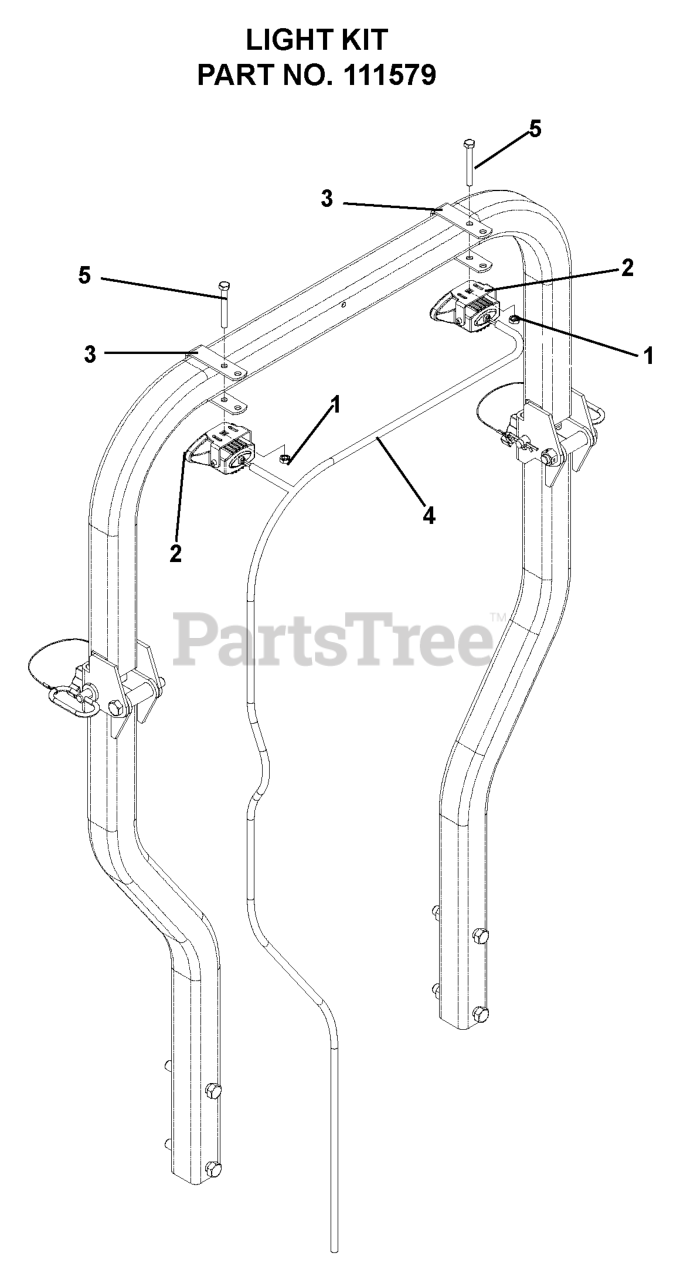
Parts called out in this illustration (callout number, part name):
1	NUT 5/16-18 HEX JAM ZD
2	LIGHT 35W W/BRKT
3	LIGHT MOUNTING BRACKET
4	LIGHT HARNESS
5	BOLT 5/16C X 2 1/2
111579	Light Kit (Accessories)
